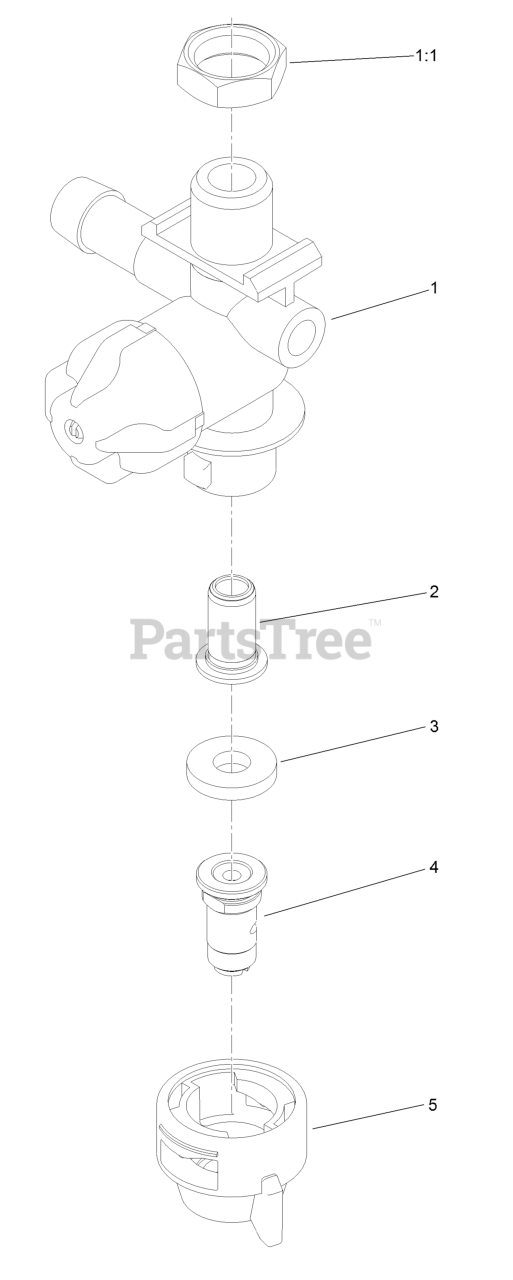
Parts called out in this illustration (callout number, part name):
1	RH Nozzle Body ASM
1:1	Nut-Nylon
2	Strainer-Tip
3	Gasket-Seal
4	Nozzle-Spray, White
5	Cap-Nozzle
99	Nozzle-Spray, Blue
99	Nozzle-Spray, Brown
99	Nozzle-Spray, Gray
99	Nozzle-Spray, Red
